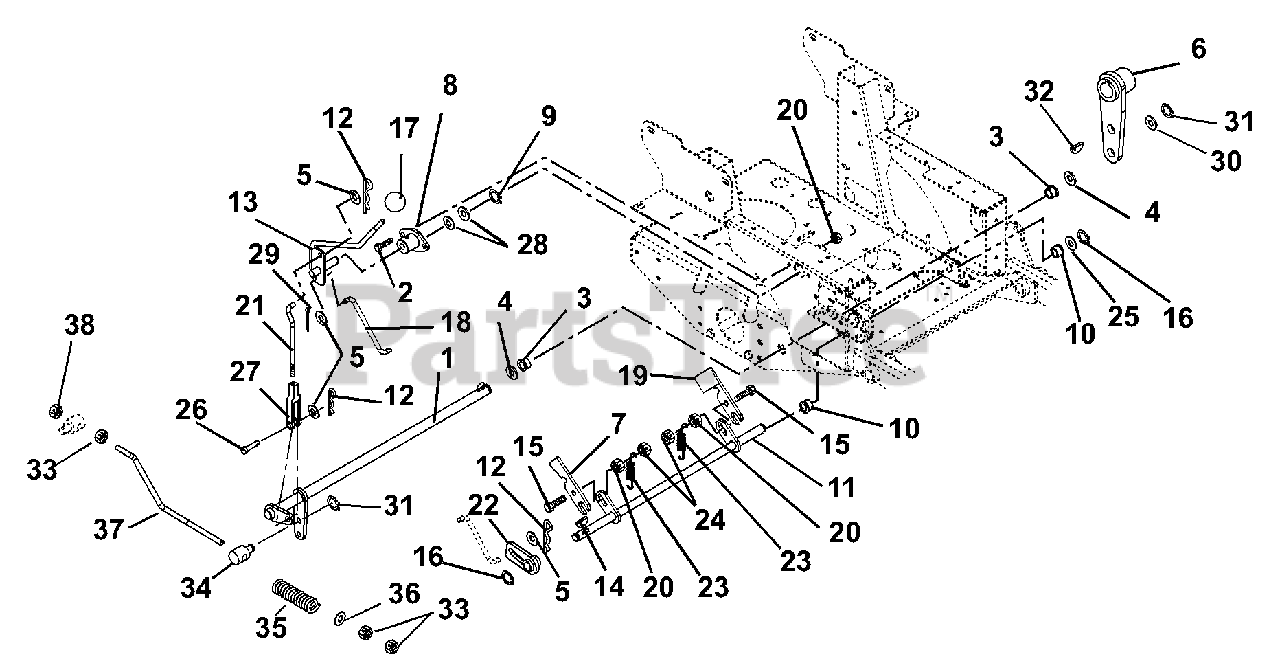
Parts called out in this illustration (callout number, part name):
1	WMT, BRAKE PIVOT
2	@BLT-HEX .31-18X1.00 GR5 YWZC
3	BSHG-FLG .762X1.0X.580X1.48 NY
4	@WSHR-FL-STL.812X1.50X.135YWZC
5	@WSHR-FL-STL.406X.812X.065 YWZ
6	WMT, BRAKE ARM
7	SLIDE, INTERLOCKING BRAKE
8	BUSHING, FLANGED
9	RG-RTNG-EXT .625X.050
10	BSHG-FLG.500X.750X.750X1.000BR
11	WMT, MECHANICAL BRAKE
12	PIN-HAIR, ENDRIES #25 YWZC
13	WMT, BRAKE ACTUATING
14	KEY-WDRF .13X.63 HRD#5
15	@BLT-RDHDSQNK .31-18X1.25 G5YZ
16	RG-RTNG-EXT .500X.050 (SNAP)
17	KNOB-STEERING LOCK
18	LINKAGE, BRAKE ACTUATING
19	INTERLOCK, SAFETY SWITCH
20	@NUT-LK-NYL-FLG .31-18 YWZC
21	LINKAGE, BRAKE COMPACT-Z
22	WMT, PARKING BRAKE HUB
23	SG-TENS .061 X .50 X 3.0 WLD 4
24	@NUT-LK-CTR .31-18 YWZC
25	WSHR-FL-STL .505X1.00X.062YWZC
26	PIN-CLEV .38X1.25 YWZC
27	CLEVIS, .38-24 ADJ.
28	WSHR-FL-STL .630X1.250X.062 YZ
29	@PIN-CTR .09X.75 EXTPRSQCT YWZ
30	WSHR-FL-STL.755X1.375X.062YWZC
31	RG-RTNG-EXT .689X.078
32	KEY-WDRF .19X.75 HRD #9
33	NUT-JAM .375-24 YWZC
34	PIN, PIVOT/TRUNNION
35	SG-COMP .142 X .710 X 2.00
36	@WSHR-FL-STL.406X.812X.065 YWZ
37	LINKAGE, BRAKE CZ
38	NUT-LK-CTR .375-24 YWZC
